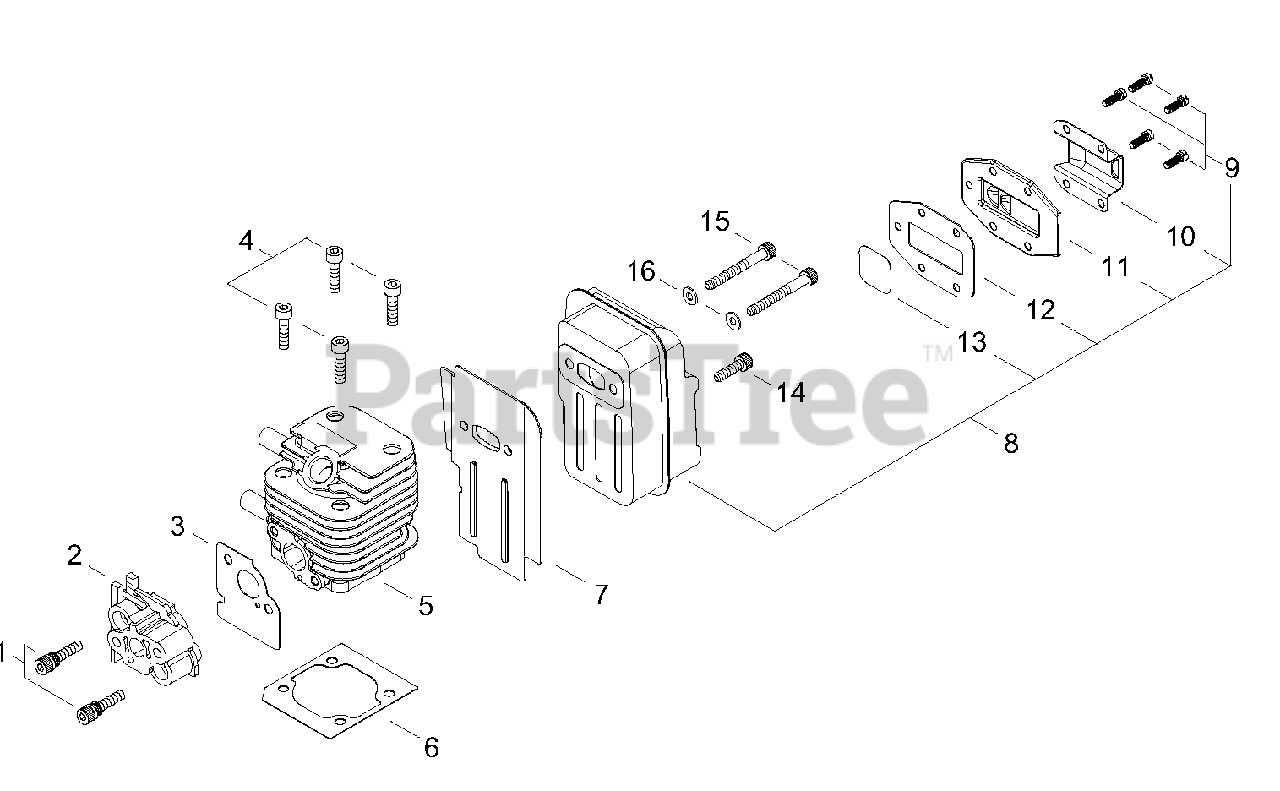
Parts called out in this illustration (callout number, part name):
1	SCREW - 5X33
2	INSULATOR
3	GASKET, INTAKE
4	SCREW - 5X16
5	CYLINDER
6	GASKET, CYLINDER
7	SHIELD, EXHAUST
8	MUFFLER ASSY
9	SCREW - 4X8
10	GUIDE, EXHAUST - OUTER
11	COVER, SPARK ARRESTER
12	GASKET, EXHAUST
13	SCREEN, SPARK ARRESTOR
14	SCREW - 5X12
15	SCREW - 5X55
16	WASHER - 5
